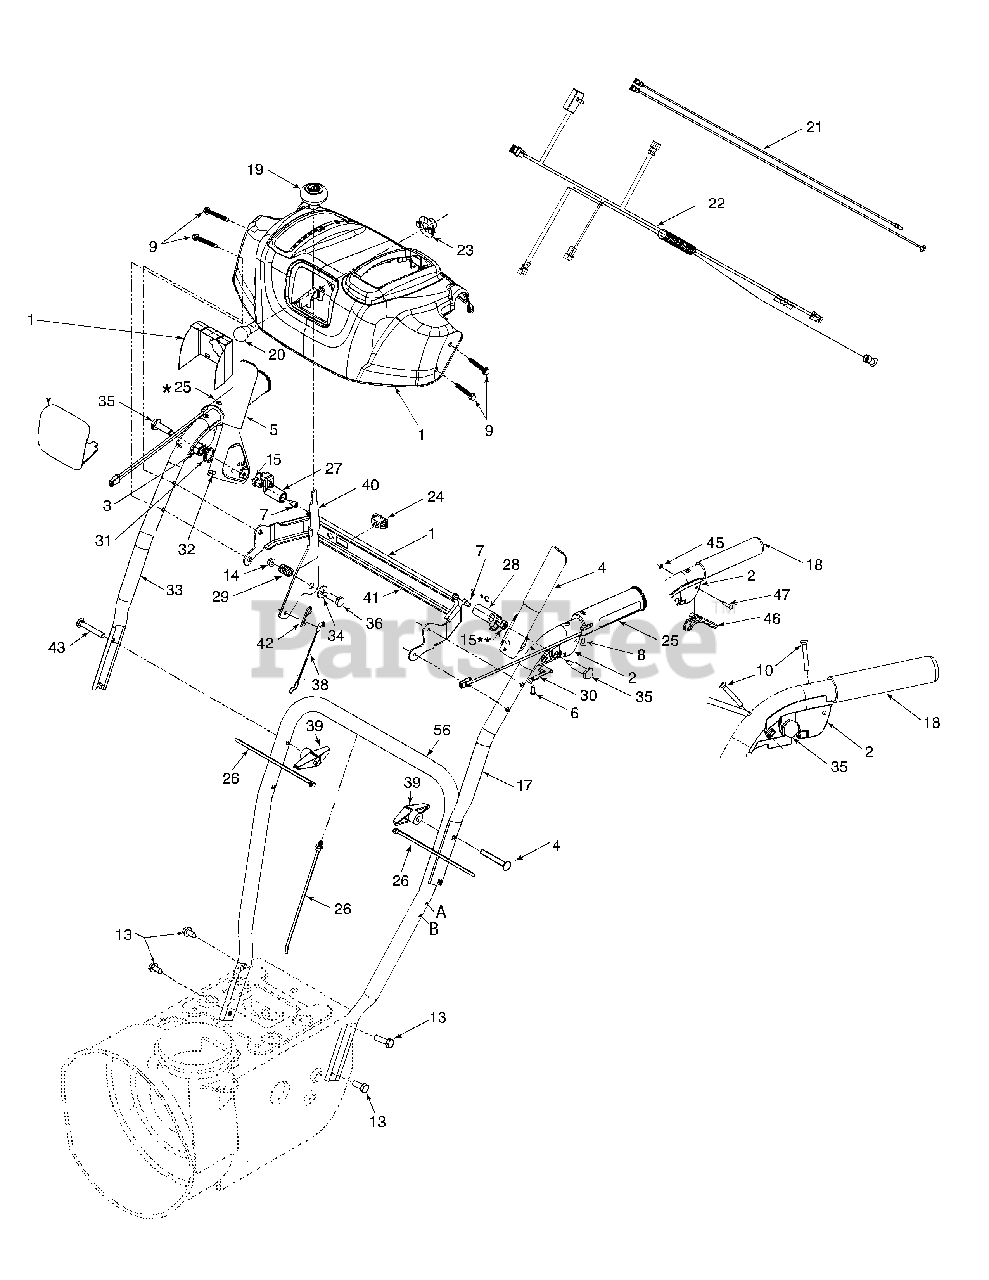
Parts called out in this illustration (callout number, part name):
1	Handle Panel Ass’y-Black w/Chute Control
2	LH Clutch Lock Handle Ass’y
3	RH Clutch Lock Handle Ass’y
4	Engagement Handle Assembly LH - Black
5	Engagement Handle Assembly RH - Black
6	Screw #8-16 x .50
7	Hex Cap Socket Screw 1/4-20 x .5
8	Oval HD C-Sunk Scr #10 x 5/8
9	Hex TT-Tap Scr 1/4-20 x 1.625
10	Oval C-Sunk Hd Screw 10-24 x 1.375
13	Hex TT Screw 3/8-16 x .75
14	Hex L-Flanged Nut 1/4-20 Gr. F Nylon
15	Hex Shoulder Nut 1/4-20
15	Hex L-Flg Nut 1/4-20 Gr. F Nylon
20	Lamp #1295
20	Lamp (208 cc/179 cc MTD engine)
22	Heated Grip Wire Harness
23	Socket
26	Cable Tie (w/plug)
28	Clutch Lock Cam
29	Compression Spring .38 ID x .88 Lg
30	Spring: Clutch Lock
31	Torsion Spring .8156 x .3038
32	Rubber Bumper
34	Flat Washer .38 ID x .87 OD x .09
35	Shoulder Screw .437 x 1.345: 1/4-20
36	Shoulder Screw .374 Dia. x 1.05 Lg.
38	Selector Speed Cable
39	Handle Knob Assembly
40	Shift Lever
41	Panel Support
42	Cotter Pin
43	Carriage Bolt 5/16-18 x 2.25
44	Lower Handle
46	Steering Control
